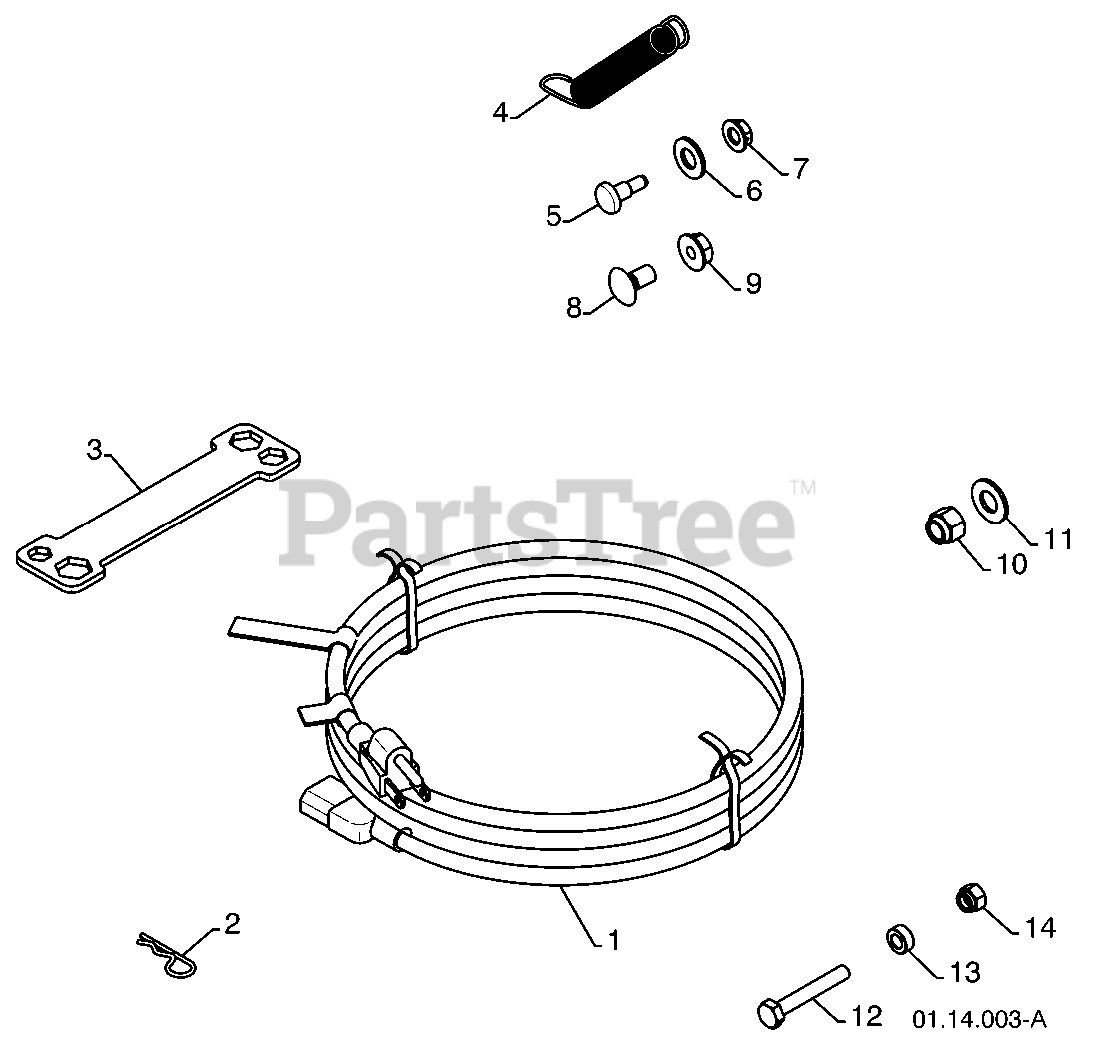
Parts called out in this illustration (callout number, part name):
1	CORD.ELECTRIC.10FT.120V.SNOW
2	SPRING RETAINER
3	RP WRENCH, SNOWTHROWER
4	SPRING.DEFLECTOR.REM.CHUTE
5	BOLT, SHOULDER
6	WASHER, NYLON FRICTION
7	NUT.HEX.FLANGE.1/4
8	BOLT
9	NUT.LOCK.5/16-18
10	NUT
11	WASHER
12	BOLT, SHEAR
13	SPACER.3943.SLEEVE.250X.47
14	LOCKNUT.NYLOC.1/4-20
